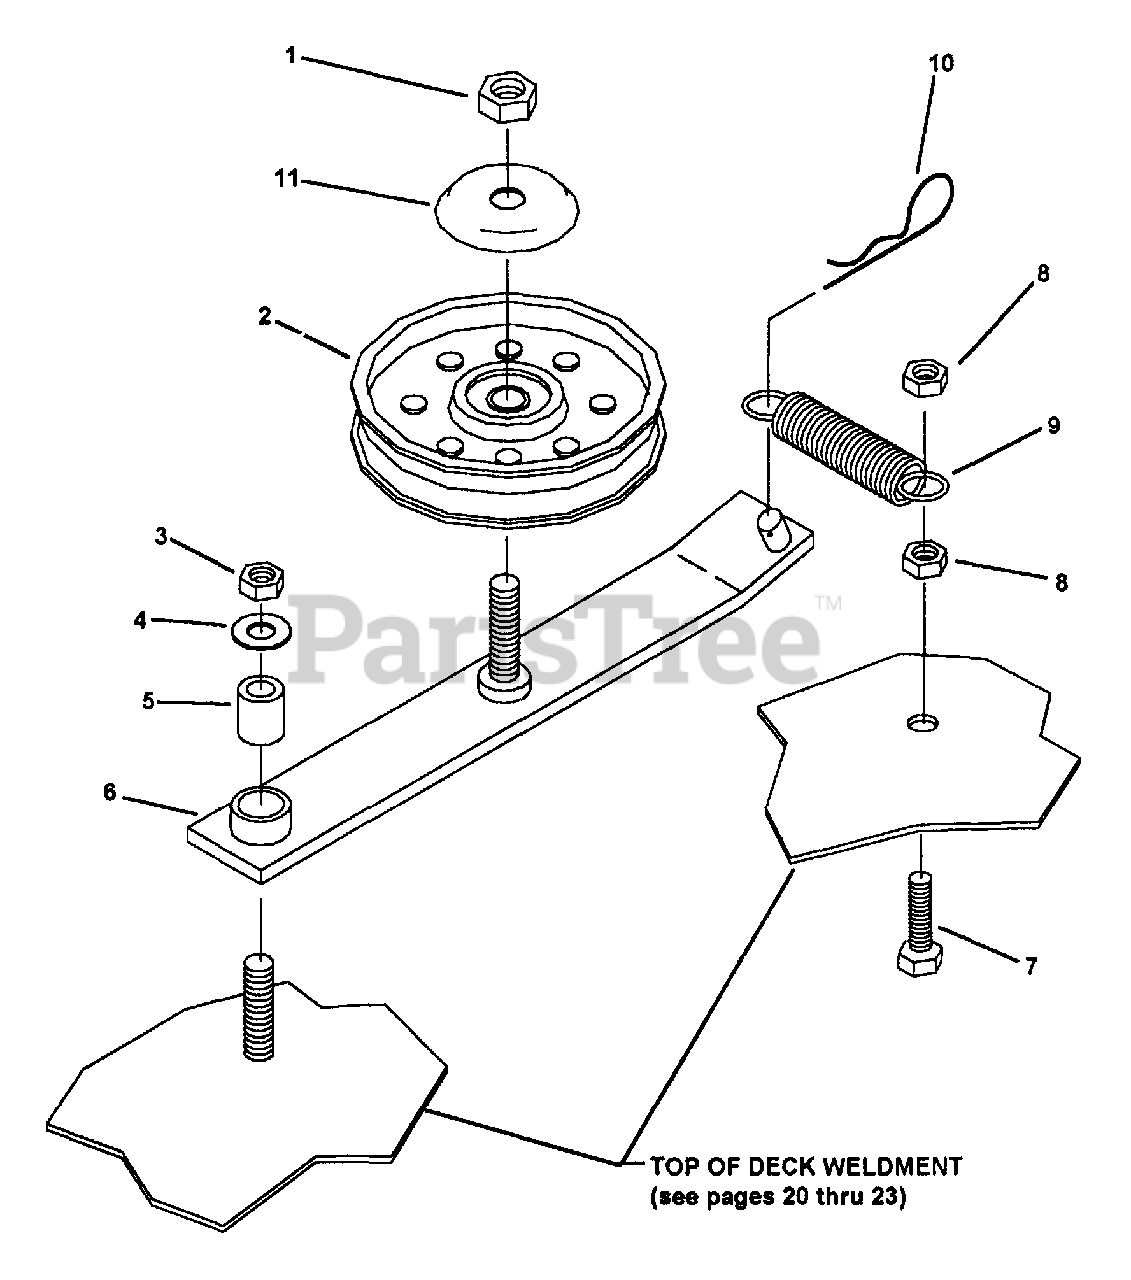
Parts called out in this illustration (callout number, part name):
1	NUT, HEX. 1/2-13 NYLOC
2	PULLEY, FLAT IDLER, 1/2 BORE, 4" O.D.
3	NUT, HEX. 3/8-16 NYLOC
4	WASHER, FLAT STD. 3/8" W SERIES
5	BEARING OILITE, 3/8 I.D. X 5/8" O.D.
6	SINGLE IDLER ARM WELDMENT, 60" DECK
7	BOLT, 3/8-24 X 1-1/4" GR. 5
8	NUT, 3/8-24, M-F LOCKNUT
9	SPRING, EXTENSION, 3/4 X 4" O.A.L.
10	PIN, HAIR SPRING, 1/8 X 2-1/2"
11	WASHER, BEARING CAP
